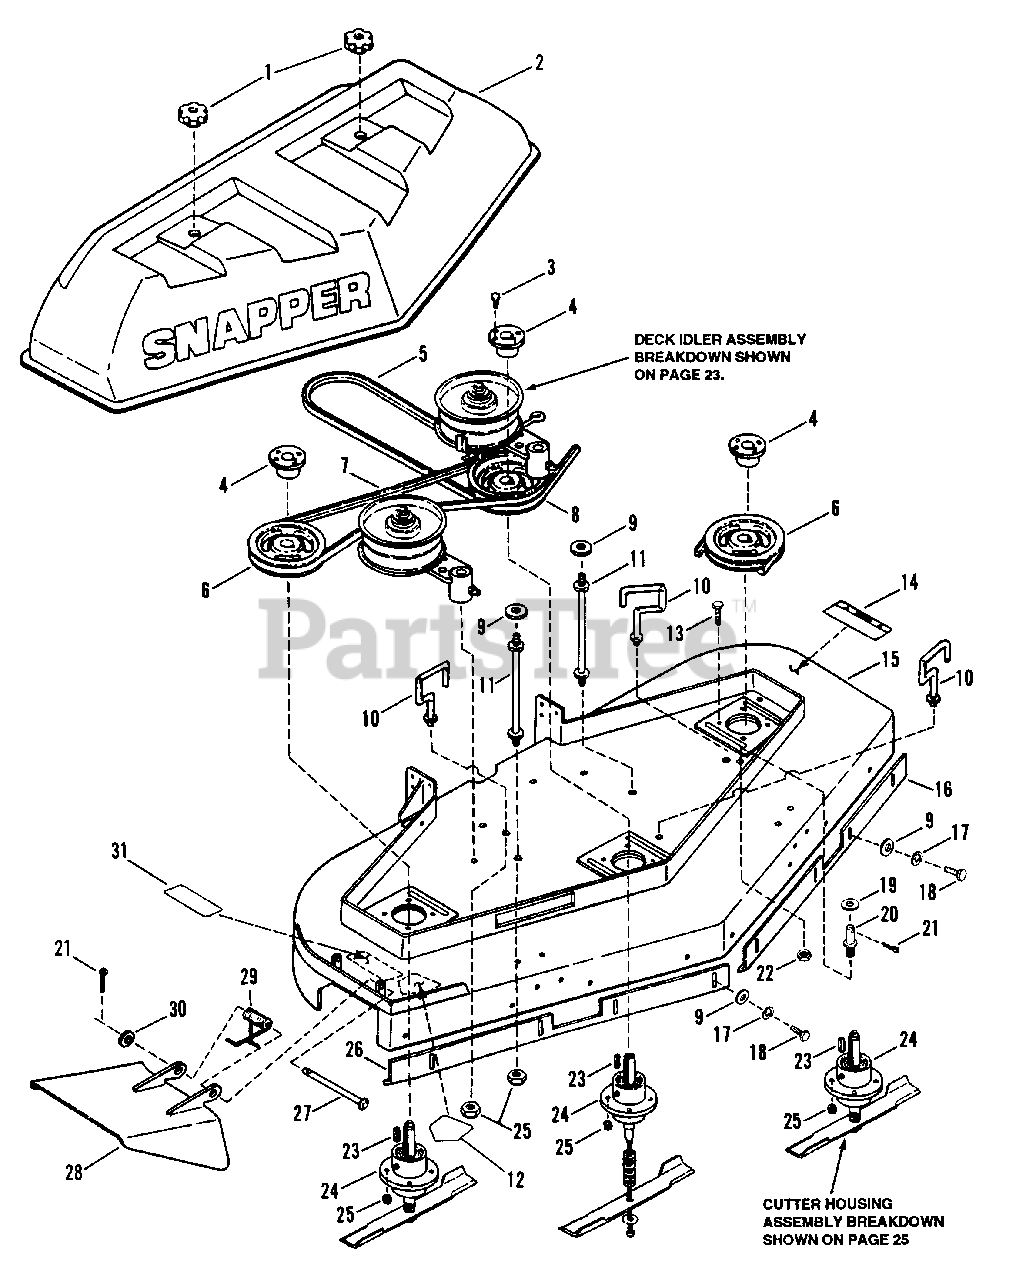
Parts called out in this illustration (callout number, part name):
1	KNOB, Hood
2	HOOD
3	BOLT, 1/4-20 x 7/8" Hex Head Cap
4	BUSHING, Taperlock
5	BELT, Engine To Deck
6	PULLEY, Cutter Blade Drive
7	BELT, Blade, 48" Deck
8	PULLEY, Cutter Blade Drive (Double Groove)
9	WASHER, 13/32" I.D. x 1-1/2" O.D.
10	GUIDE, Belt
11	STUD, Hood Mount
12	DECAL, Danger
13	BOLT, 3/8-16 X 1-1/4" GD5 CZ
14	DECAL, Caution
15	WELDMENT, 48" Deck
16	SKIRT, Front, Left Hand, 48" Deck
17	WASHER, 3/8 Split Lock
18	BOLT, 3/8-16 X 3/4" GD5 CZ
19	WASHER, 3/8" Flat
20	STUD, Clutch Link
20	STUD
21	PIN, 3/32 x 1" Cotter
22	NUT, 3/8-24 Hex Lock
23	KEY, Spindle
24	ASSEMBLY, Cutter Housing
25	NUT, 3/8-16 HEX NYLON LOCK
26	SKIRT, Front, Right Hand, 48" Deck
27	ROD, Chute Pivot
28	DEFLECTOR, Chute, 48" Deck
29	SPRING, Chute
30	WASHER, 5/16 Flat
31	DECAL, Caution
